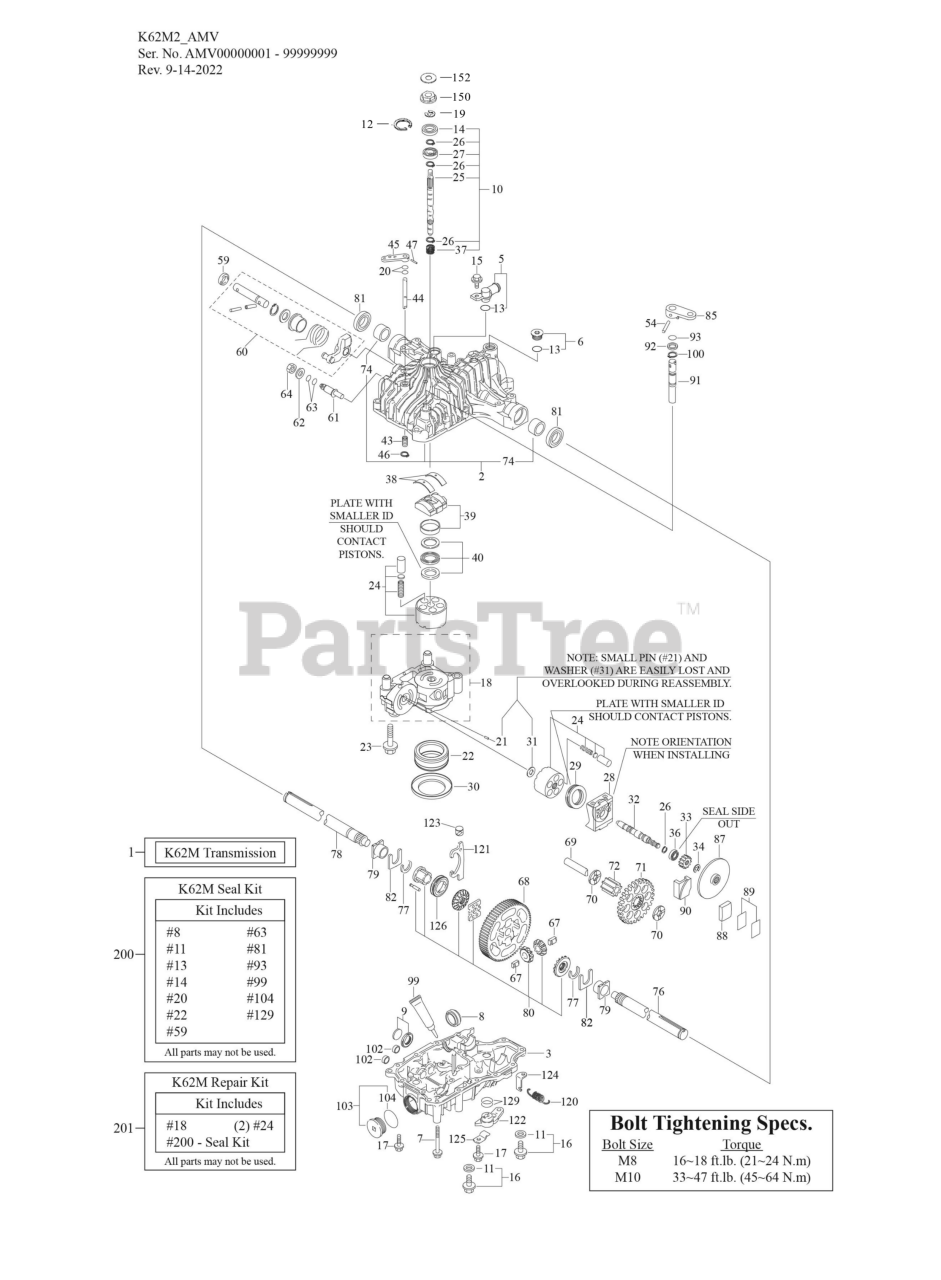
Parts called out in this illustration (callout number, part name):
1	TRANSMISSION
2	UPPER CASE KIT
3	LOWER CASE
8	FILTER, Oil
10	PUMP SHAFT KIT
16	DRAIN BOLT KIT
22	FILTER, Oil
24	PUMP, Oil
26	RING, Locking
28	HOUSING, Motor
30	FILTER CAP
32	MOTOR SHAFT
33	MOTOR GEAR
34	E-RING
37	PUMP SPRING
38	THRUST, Metal
40	THRUST BEARING KIT
44	BYPASS SHAFT
54	ROLL PIN 6 * 40
60	CONTROL SHAFT KIT
61	FULCRUM
67	DIFFERENTIAL PINION PIN
69	FINAL PINION SHAFT
76	AXLE SHAFT LEFT
77	RING, Locking
79	BUSHING
80	DIFFERENTIAL LOCK KIT
82	WASHER, Thrust
88	SHOE, Brake
91	BRAKE SHAFT
99	SEALANT
103	COVER, Oil Filter
121	DIFFERENTIAL LOCK FORK
123	LEVER PIVOT
125	LEVER CLIP
126	DIFFERENTIAL LOCK SLIDER
150	NUT, LOCK
200	SEAL KIT
201	REPAIR KIT
